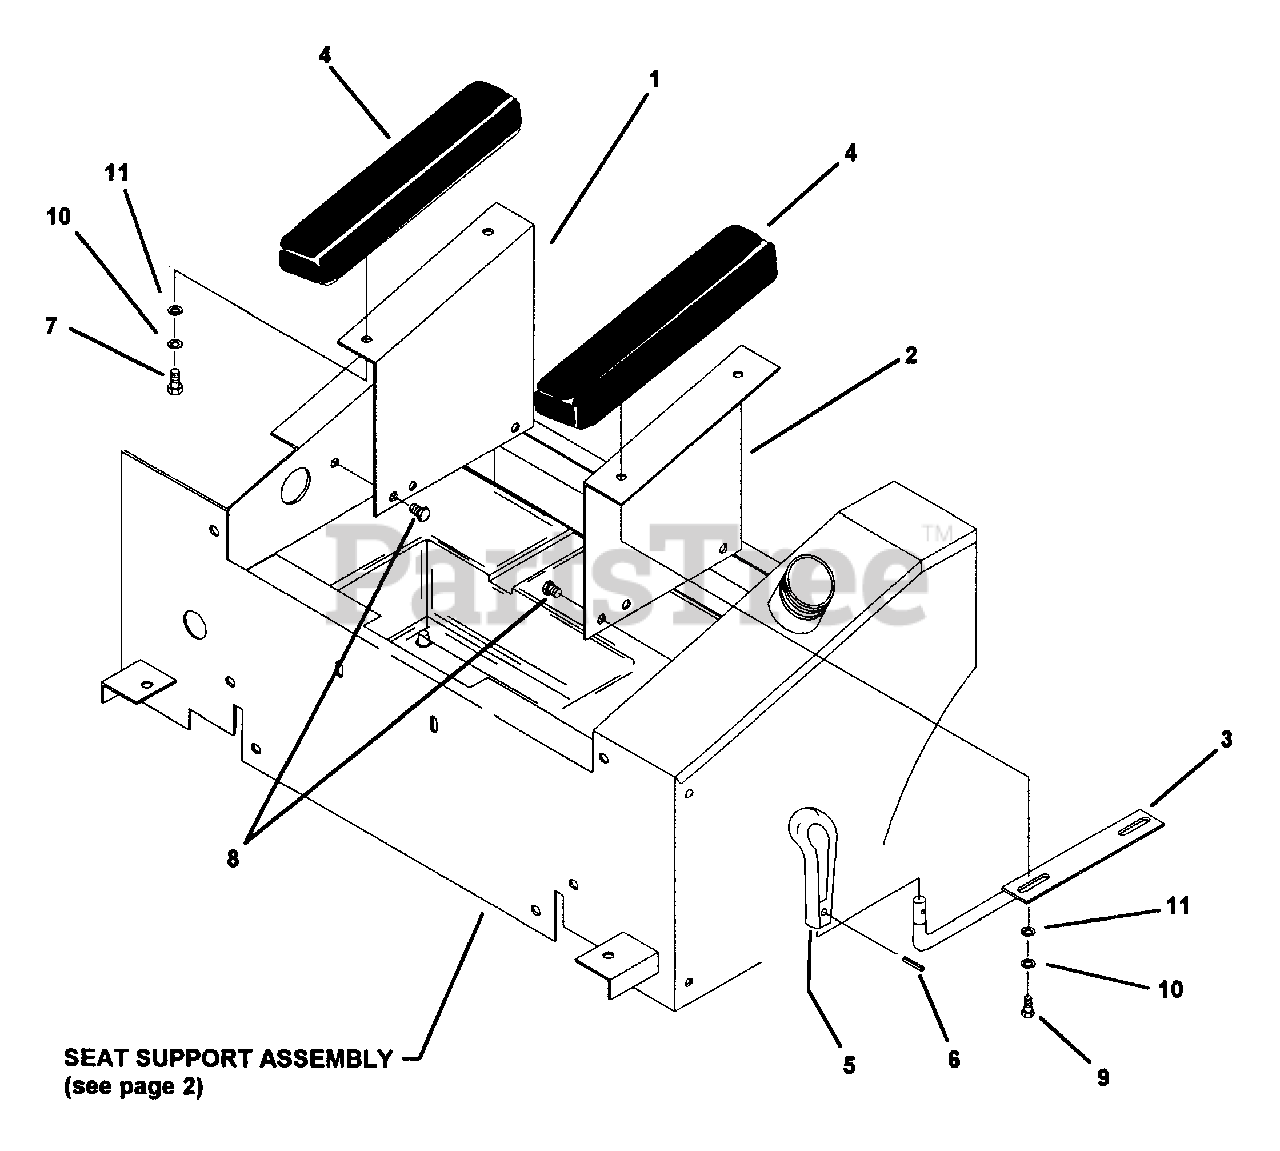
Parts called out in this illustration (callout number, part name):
1	ARM REST SUPPORT R.H.
2	ARM REST SUPPORT L.H.
3	SECURITY HANDLE WELDMENT
4	ARMREST PAD ASSEMBLY
5	HANDLE, JOYSTICK, 7/16" BORE
6	PIN, SPIRAL 3/16 X 1" LIGHT DUTY
7	BOLT, 5/16-18 X 3/4" GR. 5
8	BOLT, 3/8-16 X 1/2" NYLON PATCH
9	BOLT, 5/16-18 X 1" GR. 5
10	LOCKWASHER, 5/16" HEAVY SPRING
11	WASHER, FLAT STD. 5/16"
